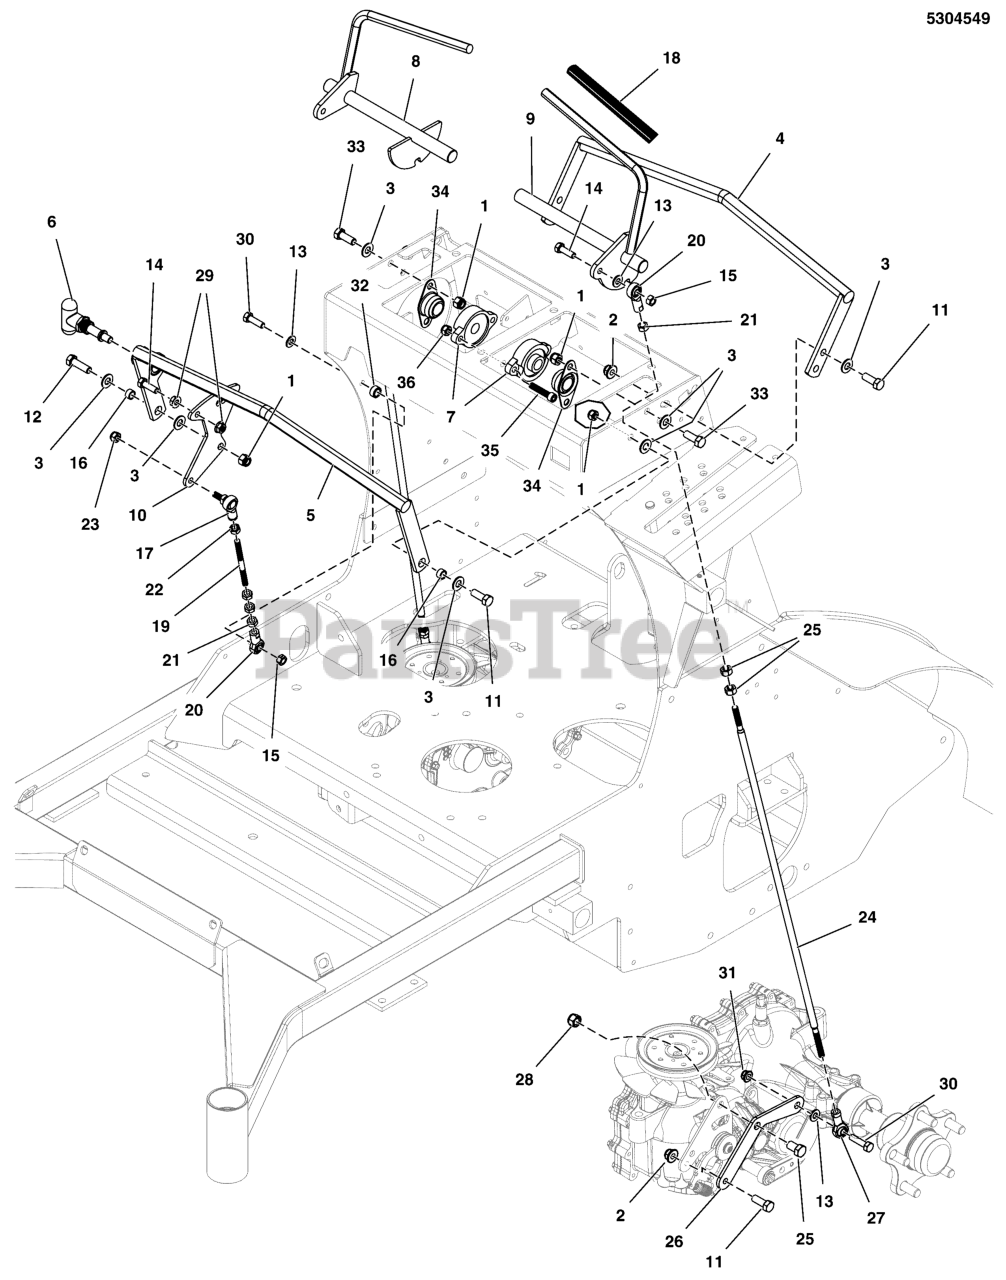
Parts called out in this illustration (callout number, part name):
1	NUT, 3/8-16 HEX NYLON LOCK
2	NUT, 3/8-16 HEX NYLOCK FLANGE
3	WASHER, 3/8 SAE
4	WELD, REAR HANDLE, SRSZ1 - BLK
5	WELD, FRONT HANDLE, SRSZ1 - BLK
6	PULL PIN, 3/8" DIA X 9/16" STROKE
7	BEARING-FLANGE, 5/8
8	WELD, CONTROL HANDLE, SRSZ1 RH - BLK
9	WELD, CONTROL HANDLE, SRSZ1 LH - BLK
10	PLATE, SPEED ADJUSTMENT, SRS - BLK
11	BOLT, 3/8-16 X 1" GD5 CZ
12	BOLT, 3/8-16 X 1-1/4" GD5 CZ
13	WASHER, 5/16" SAE
14	BOLT, 5/16-18 X 1 GD5 CZ
15	NUT, 5/16-18, HEX, CNTR LK,ZINC PHOS/OIL
16	SPACER, .38 X .50 X .27, CZ
17	BALL JOINT 5/16-24 LH FEMALE W/STUD, BR
18	GRIP, FOAM, .475 X 7.75 X .095
19	ROD, 5/16-24 X 4.25, CZ
20	BALL JOINT 5/16-24 RH FEMALE BRONZE RACE
21	NUT, 5/16-24 HEX
22	NUT, 5/16-24 HEX, LH
23	NUT, 5/16-24 HEX NYLON LOCK
24	ROD, MOTION CONTROL, STAND-ON
25	BOLT, 7/16-14 X 3/4, GD 5 CZ
26	PLATE, CONTROL MOUNT - BLK
27	BALL JOINT 5/16-24 LH FEMALE BRONZE RACE
28	NUT, 7/16-14 HEX TOP LOCK
29	NUT, 5/16-18 HEX SERRATED FLANGE (SMALL)
30	BOLT, 5/16-18 X 1-1/4 GD5 CZ
31	NUT, 5/16-18 HEX NYLOCK FLANGE
32	SPACER, .33 X .50 X .25, PM, CZ
33	BOLT, 3/8-16 X 3/4" GD5 CZ
34	BEARING, BRONZE, FLANGED, 5/8", FLB10
35	SCREW, SOC HD, 5/16-18 X 1-1/2, BLK
36	NUT, 5/16-18 HEX NYLON LOCK
